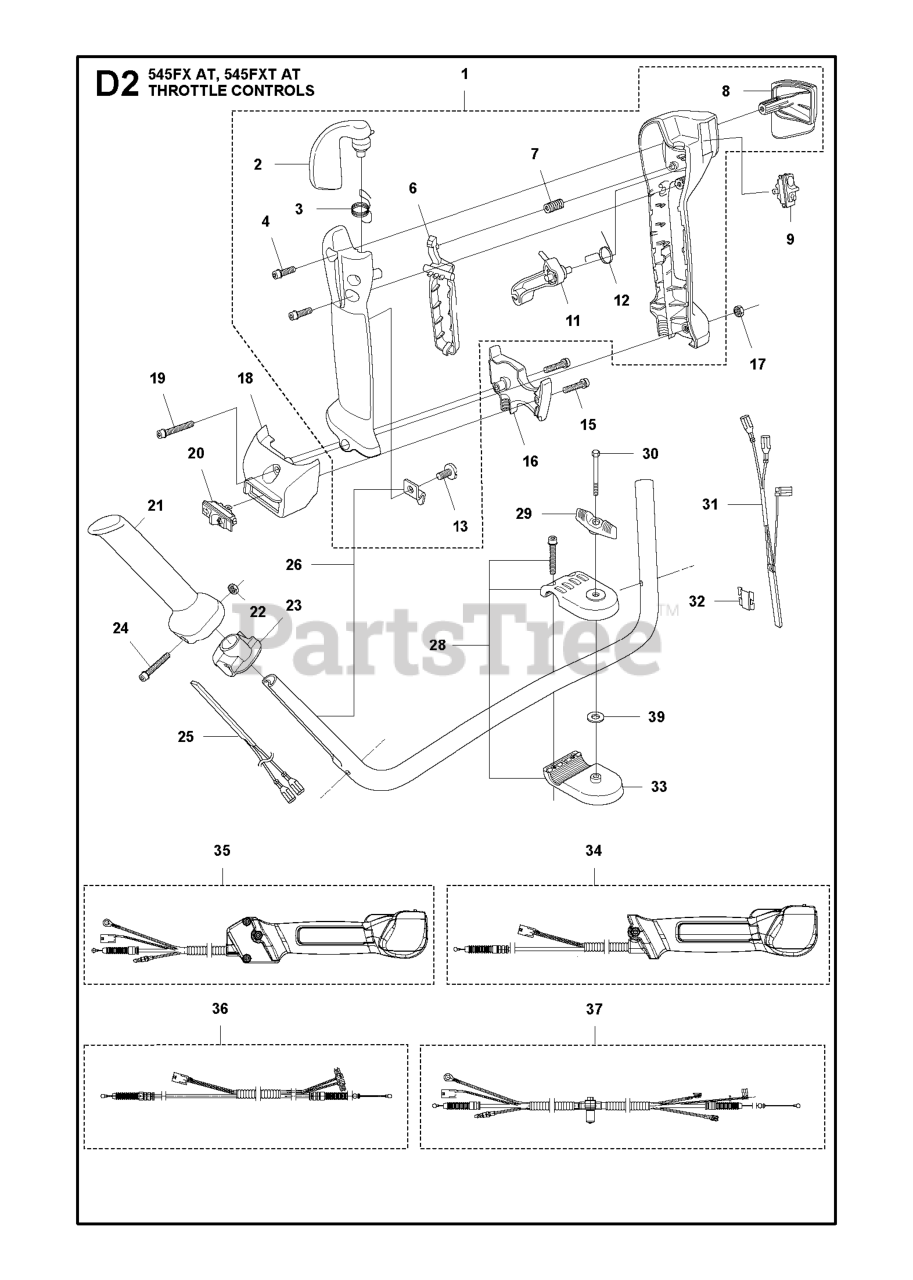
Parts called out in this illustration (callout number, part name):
1	THROTTLE HANDLE
2	THROTTLE TRIGGER
6	THROTTLE LOCK
9	STOP BUTTON
15	SCREW IHSCT MT4X18 10.9 ZN/FE
16	HOLDER
17	NUT M6M M5
18	HOLDER
19	SCREW IHSCFM
19	SCREW IHSCFM M5X45 10.9 ZN/FE
20	SWITCH (G)
21	HANDLE
22	NUT M6M M5
25	HEATING ELEMENT
26	KIT
28	HANDLEBAR BRACKET KIT
28	HANDLEBAR BRACKET SPARE PART K
31	HEATING ELEMENT
32	HOLDER
33	HANDLE HOLDER LOWER
